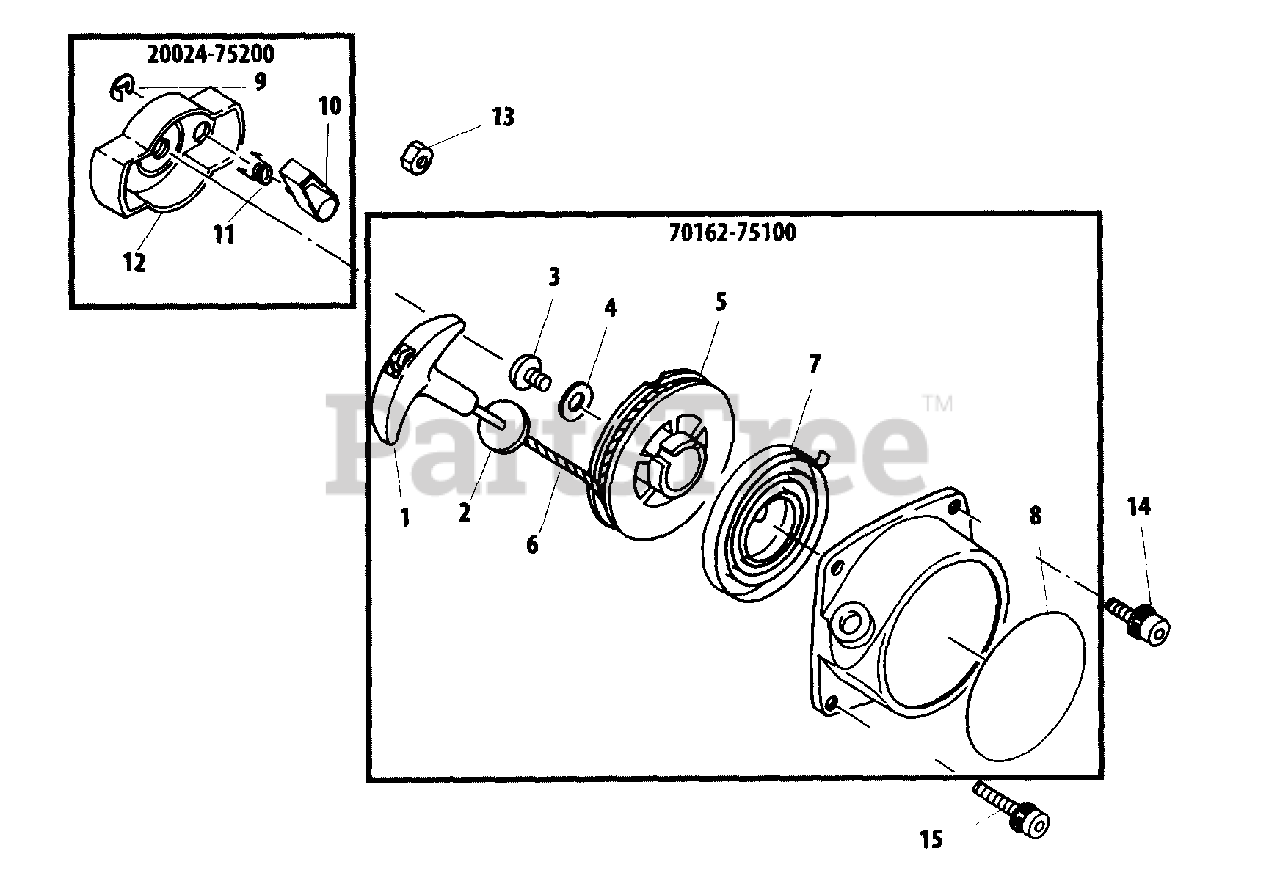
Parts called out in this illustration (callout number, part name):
1	GRIP, STARTER
2	DAMPER
3	SCREW 5
4	WASHER
5	REEL, ROPE
6	ROPE, STARTER
7	SPRING, RECOIL
8	LABEL, TRADE
9	E-RING 4
10	PAWL, STARTER
11	SPRING, RETURN
12	PULLEY, STARTER
13	NUT
14	BOLT M5×16
15	BOLT M5×25
20024-75200	PULLEY ASSY, STARTER
70162-75100	STARTER ASSY
